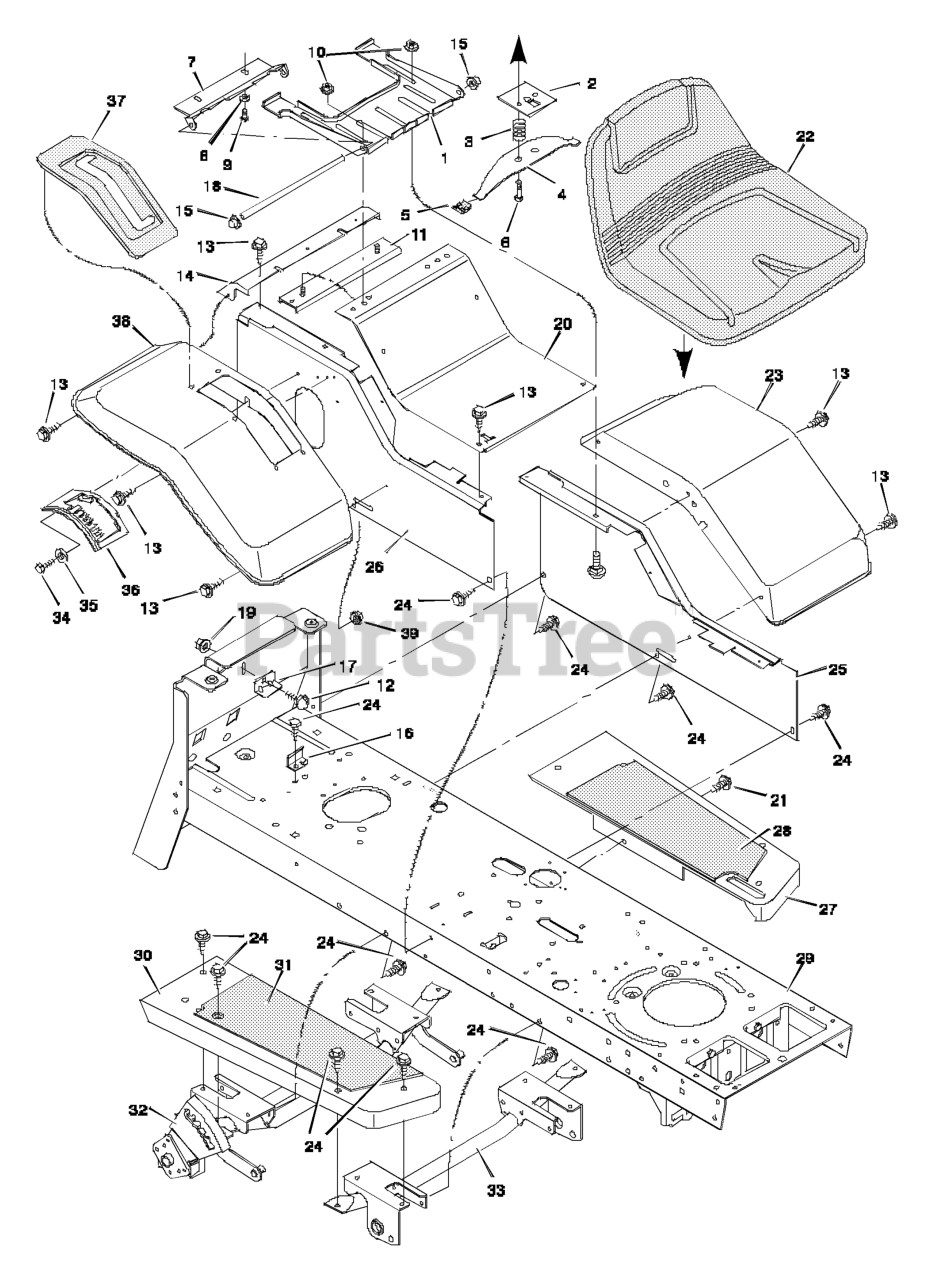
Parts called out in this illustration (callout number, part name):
1	Bracket, Seat
2	Plate Assembly, Switch
3	Spring, Compression
4	Spring, Seat
5	Glide, Spring
6	Bolt, Shoulder
7	Support, Seat
8	Lockwasher
9	Bolt, Hex
10	Locknut, Flange
11	Channel Assembly
12	Bolt, Carriage
14	Insert, Rear
15	Push On Cap
16	Clip, Battery
17	Clamp, Battery
18	Rod, Pivot
19	Locknut
20	Panel, Top
21	Fastener, Panel
25	Panel, Left
26	Panel, Right
27	Running Board, Left
28	Mat, Left
29	Frame Channel
30	Running Board, Right
31	Mat, Right
32	Lifter and Support Assembly
33	Support Assembly, Front
35	Washer
36	Gate, Shift
37	Cover, Shift
38	Fender, Right
39	Locknut
